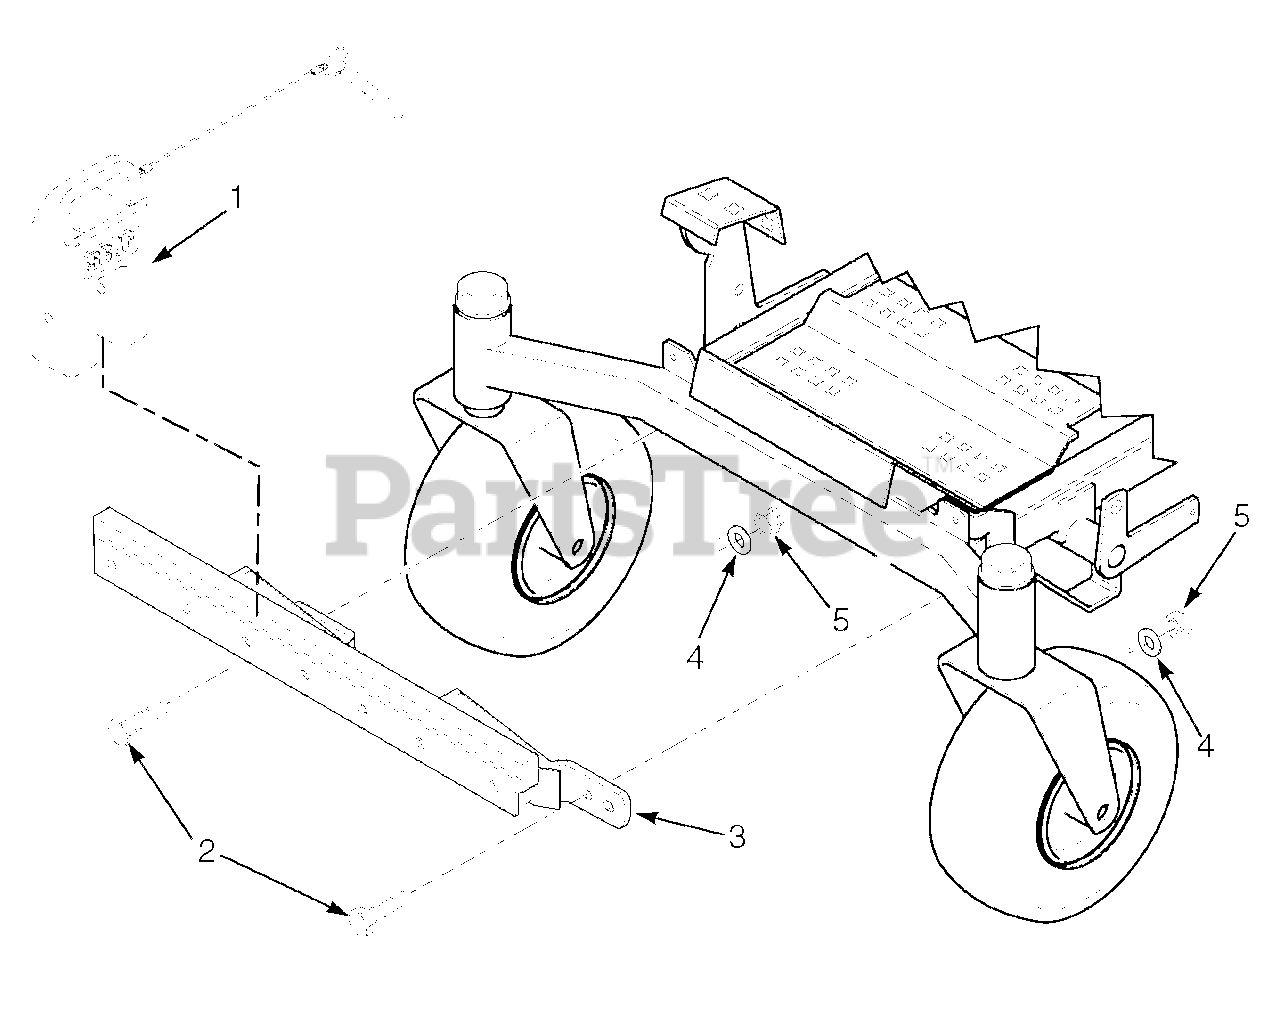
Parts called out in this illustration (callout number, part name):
1	Weight Assembly
2	Bolt, Hex Head 7/16-14 x 1-3/4"
3	Support Weldment, Weights
4	Flatwasher, 7/16-.500 x 1-1/4"
5	Nut, Elastic Stop 7/16-14
